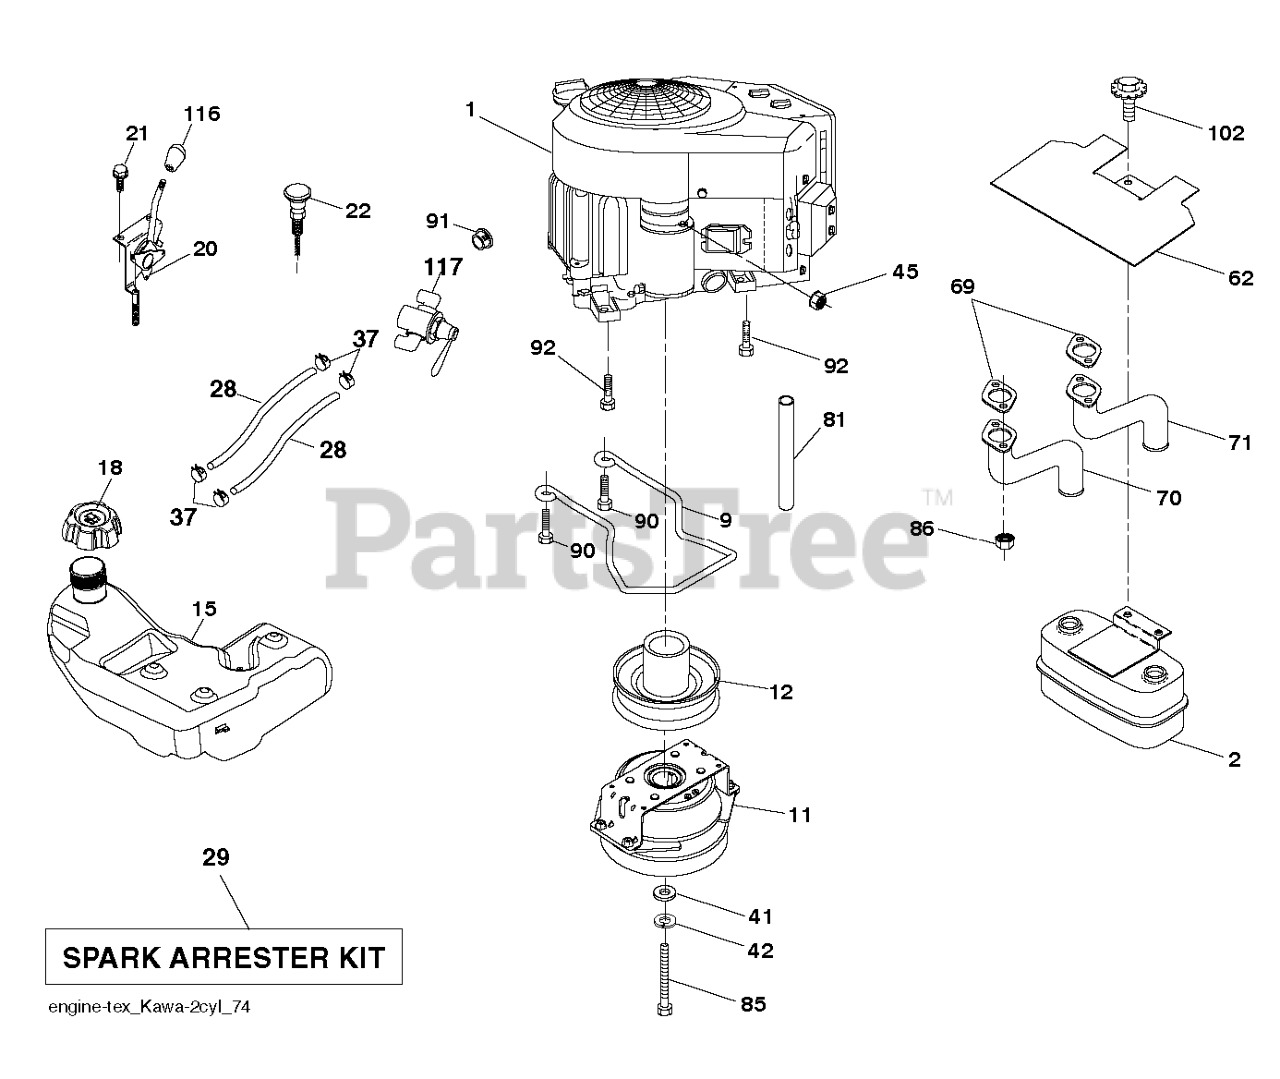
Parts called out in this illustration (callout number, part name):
2	MUFFLER.ASM.TWIN.MNTG.BRACKET
11	CLUTCH.OGURA.5.0PD.GT1.5A-EH01
12	PULLEY ENGINE
15	TANK FUEL
15	TANK.FUEL.4GAL
18	CAP.ASSY.FUEL.3".N-EPA.GRY.498
20	CONTROL.THROTTLE.PRO.
22	CONTROL.CHOKE.ERGO.BLACK
28	HOSE 1/4" LOW PERMEATION FUEL
29	KIT.SPARK ARRESTOR 794945 B&S
37	HOSE CLAMP
62	SERVICE KIT HEAT SHIELD
70	TUBE.EXHAUST.LH.FR961/FR730
71	TUBE.EXHAUST.RH.FR961/FR730
81	TUBE, DRAIN OIL ASM.
85	BOLT.HEX.7/16-20X3.GR5.YELLOW
86	NUT.HEX.FLANGE.TOPLOCK
90	SCREW 3/8-16X1
91	BUSHING.1.375OD
92	SCREW 3/8-16X1
102	BOLT.HEX.HD.WASHER.5/16-18X.75
116	KNOB - SHIFT
117	VALVE FUEL RESERVE
